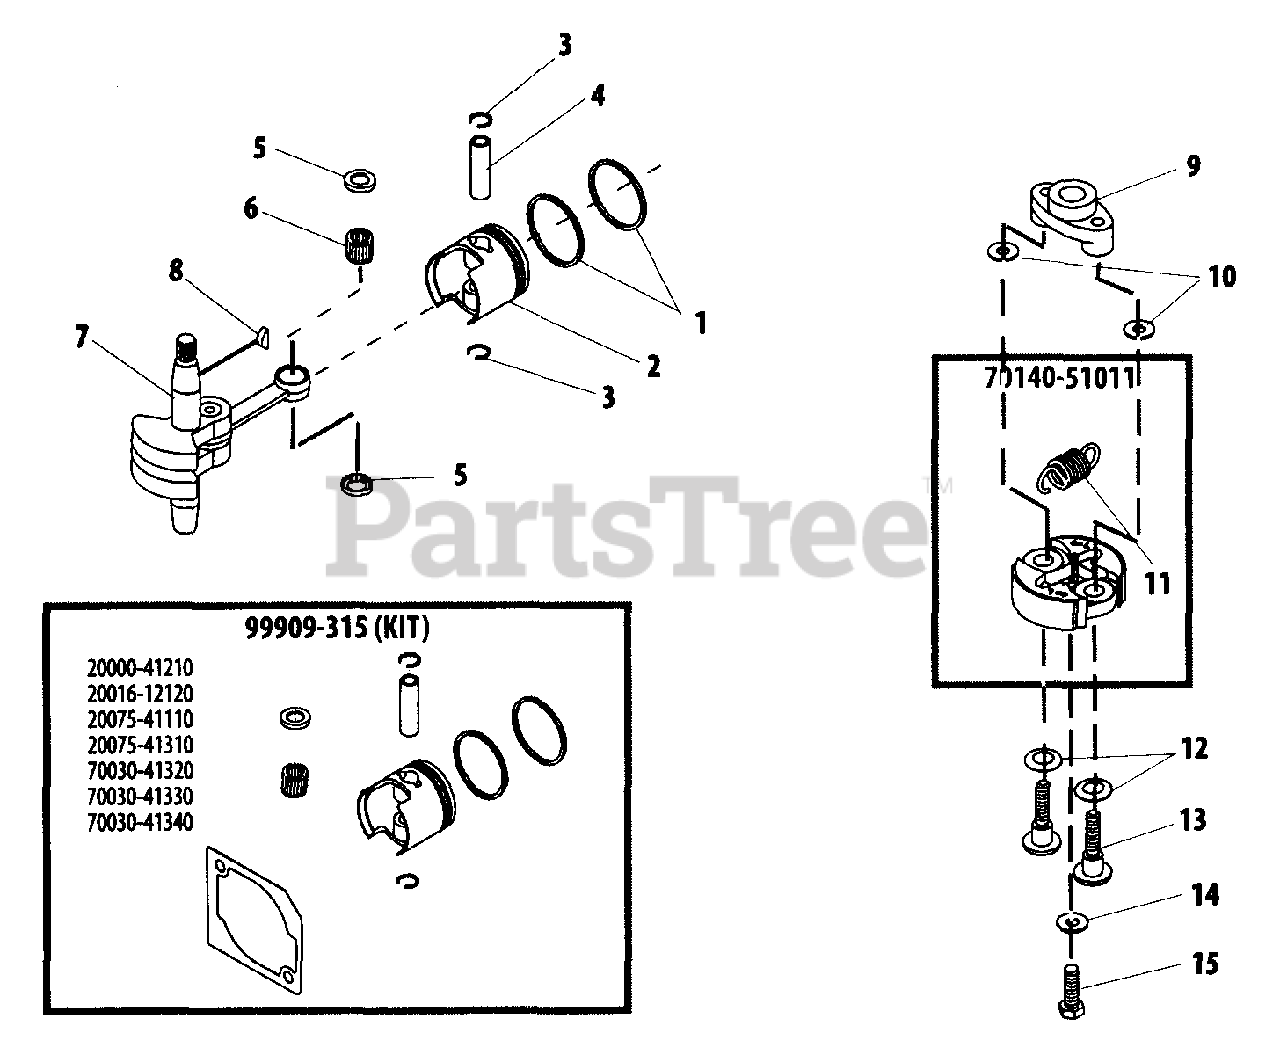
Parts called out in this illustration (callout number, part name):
1	RING, PISTON
2	PISTON
3	RING, SNAP
4	PIN, PISTON 8
5	WASHER, THRUST
6	BEARING, NEEDLE
7	CRANKSHAFT ASSY
8	KEY, WOODRUFF 3×10
9	HUB, CLUTCH
10	WASHER 6 MM
11	SPRING, CLUTCH
12	WASHER, SPRING
13	BOLT, CLUTCH
14	WASHER 6 MM
15	BOLT M6×18
70140-51011	CLUTCH SHOE ASSY
99909-315	PISTON ASSY
